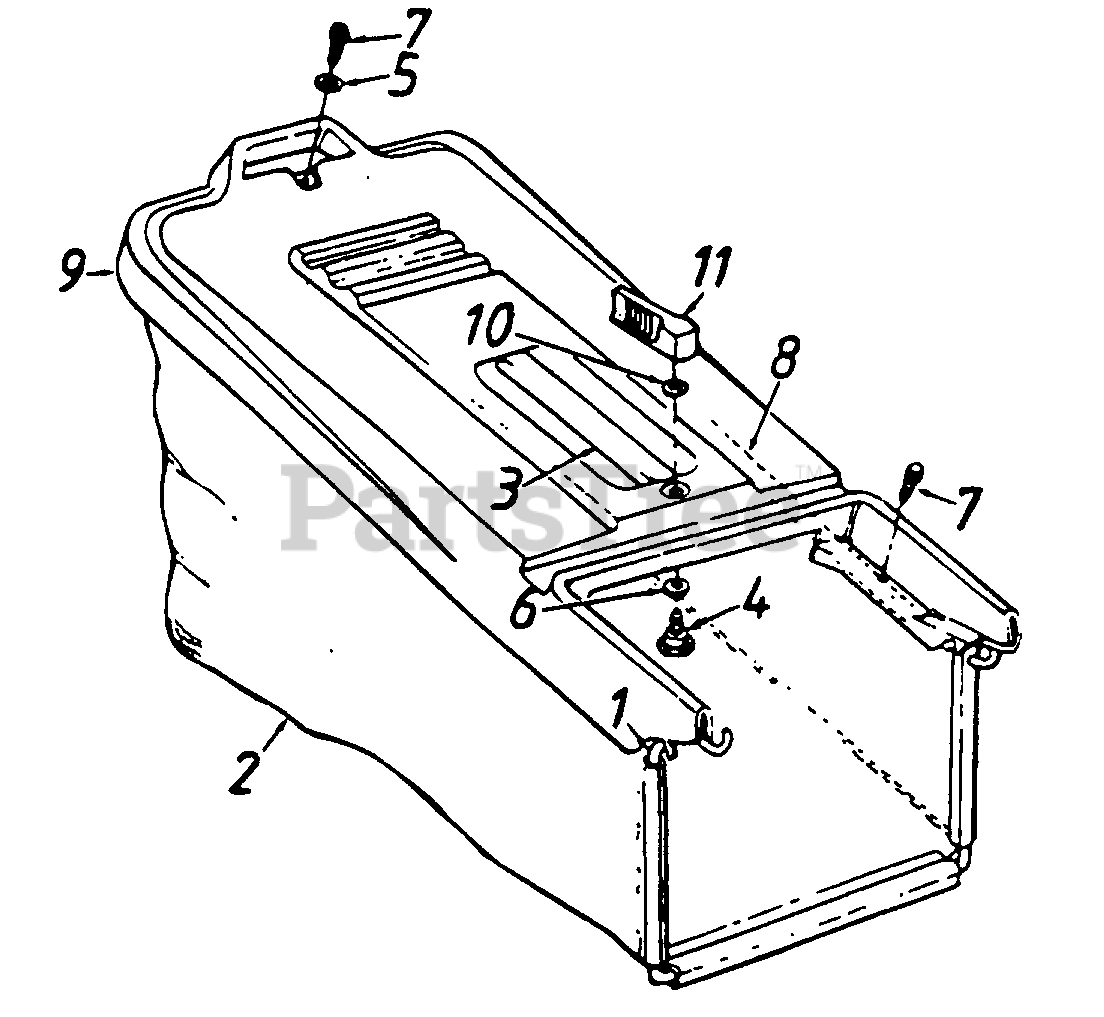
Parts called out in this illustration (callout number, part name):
2	Grass Bag
3	Hardtop Handle
4	Shoulder Bolt
5	Fl-Wash. .281" I.D.
6	Bowed Washer
7	Hex L-Wash. AB-Tap Scr. 1/4 x .62"
10	Internal L-Wash. 1/4" I.D.
11	Locking Knob
